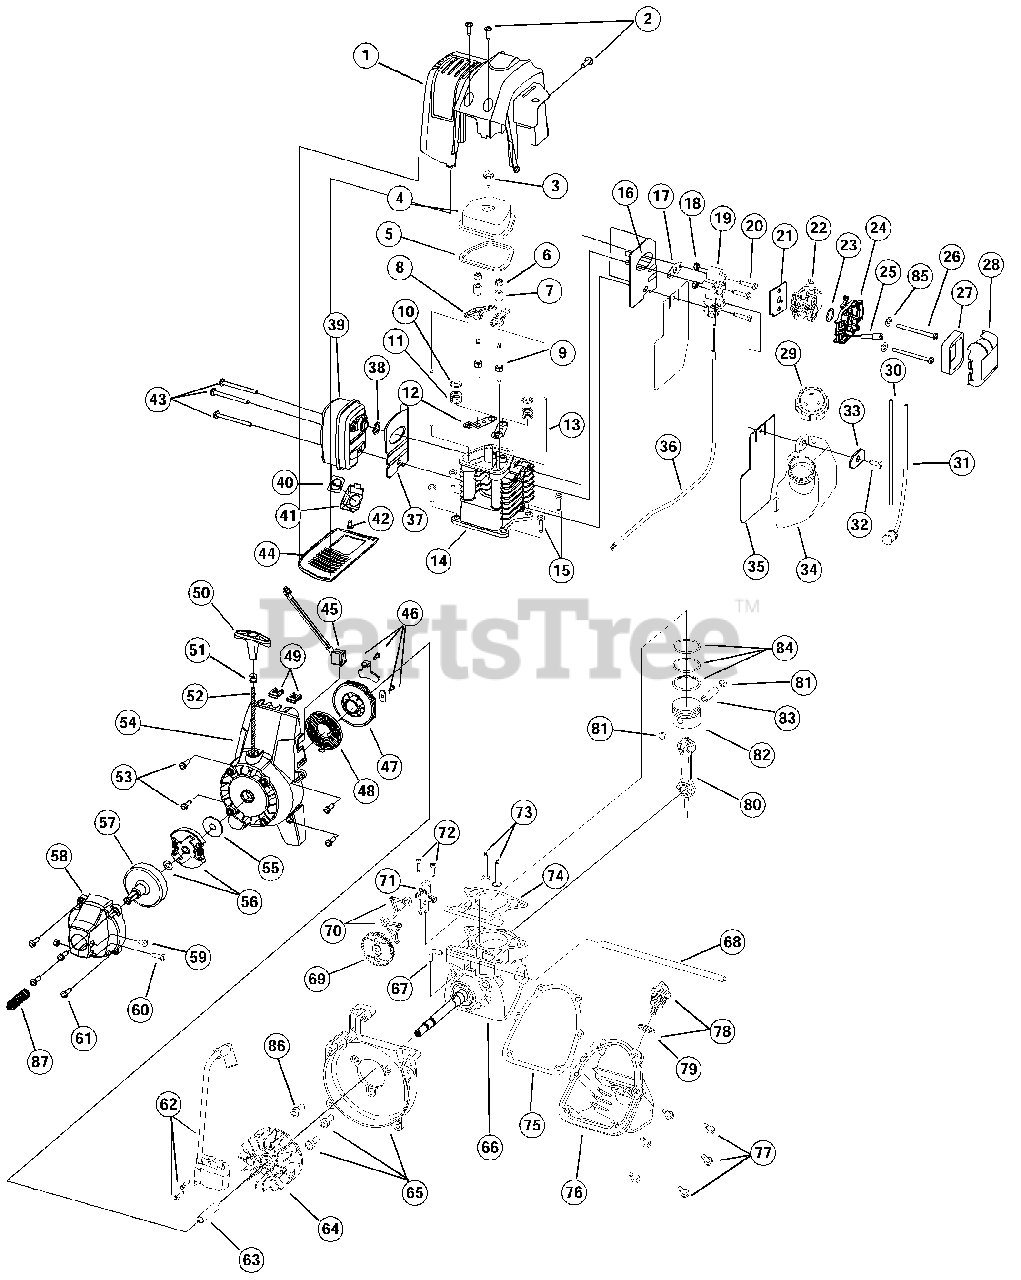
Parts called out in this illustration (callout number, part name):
1	Engine Cover
2	Engine Cover Screws
3	Valve Cover Screw
4	Valve Cover
5	Valve Cover Gasket
6	Rocker Adjustment Nut
7	Rocker Arm Pivot
8	Rocker Arm
9	Rocker Arm Stud
10	Valve Spring Retainer
11	Valve Spring
12	Push Rod Guide
13	Push Rod
14	Cylinder Head Assembly
15	Cylinder Screw
16	Intake Baffle
17	Carburetor Mount Gasket
18	Nut
19	Carburetor Mount
20	Carburetor Mount Screw
21	Carburetor Gasket
22	Carburetor with Primer
23	O-Ring, Carburetor
24	Air Filter/Choke Assembly
25	Breather Tube
26	Air Filter Mounting Screw
27	Air Filter
28	Air Filter Cover
29	Fuel Cap
30	Fuel Return Line
31	Fuel Pick-Up Line with Filter
34	Fuel Tank Assembly
35	Fuel Tank Shield
36	Throttle Cable
37	Muffler Baffle
38	Muffler
39	Muffler Gasket
40	Spark Arrestor Screen
41	Screen Cover
43	Muffler Mounting Screw
44	Muffler Cover
45	Switch with Wires
46	Pulley Retainer Assembly
47	Recoil Pulley
48	Recoil Spring
49	Nut Clip
50	Pull Handle
51	Rope Guide
53	Starter Housing Screw
54	Starter Housing Assembly
55	Clutch Washer
56	Clutch with Spacer
57	Clutch Drum
58	Clutch Cover
59	Anti-Rotation Screw
60	Screw
61	Clutch Cover Screw
62	Ignition Module with Screws
64	Flywheel
65	Shroud Assembly w/Screws
66	Crankcase Assembly
67	90° Elbow
68	Breather Hose
69	Cam Gear
70	Cam Follower
71	Cam Bracket
72	Cam Bracket Screw
73	Valves, Intake and Exhaust
74	Cylinder Gasket
75	Oil Pan Gasket
76	Oil Pan
77	Oil Pan Screw
78	Dipstick Assembly
80	Connecting Rod
81	Wrist Pin Button
82	Piston
83	Wrist Pin
84	Piston Ring Set
87	Compression Spring
